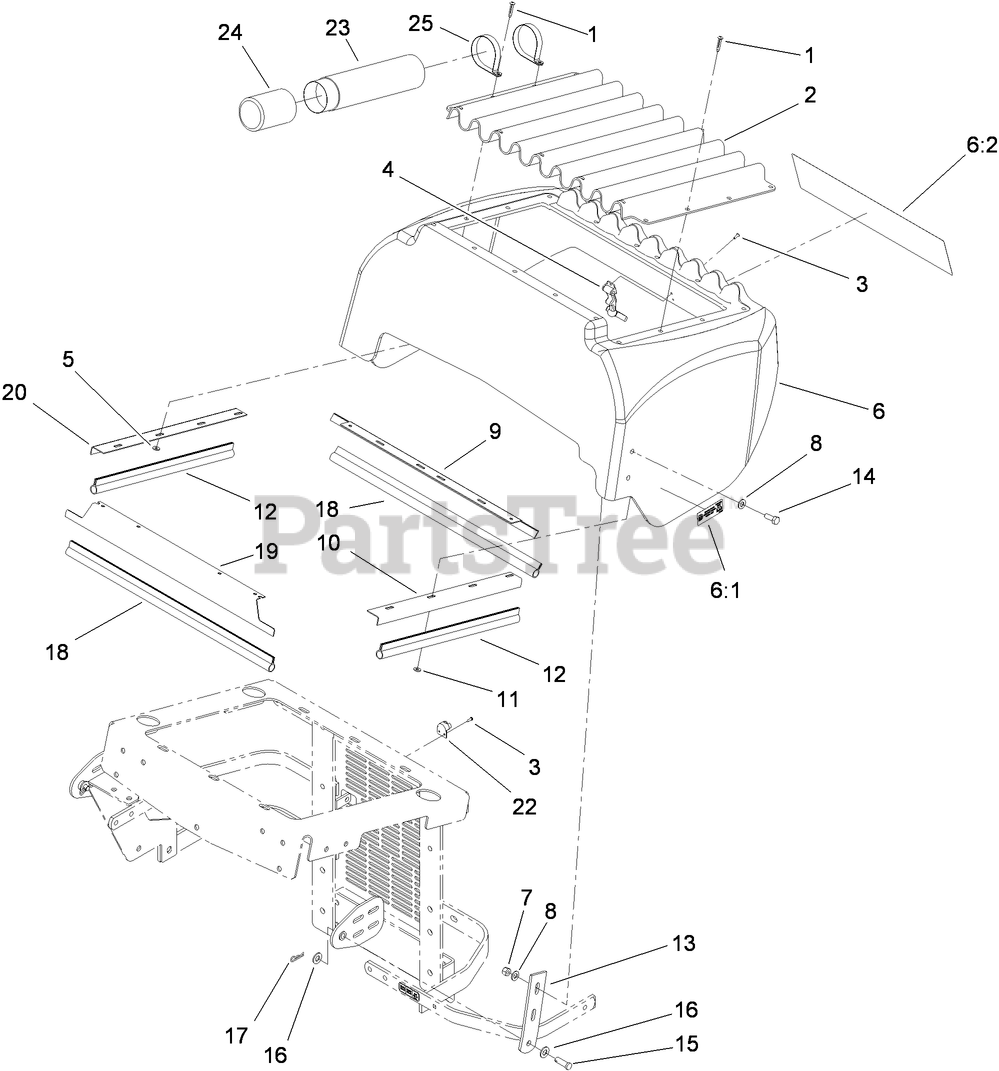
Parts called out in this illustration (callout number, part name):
2	SCREEN-RADIATOR
3	RIVET
4	LATCH-RUBBER
5	WASHER-SPRING
6	HOOD ASM
6:1	DECAL-LOW SULFUR
7	NUT-LOCK, NI
8	WASHER-PLAIN
9	ANGLE-RADIATOR, BOTTOM
10	ANGLE-RADIATOR, LH
11	WASHER-FLAT
12	SEAL-TRIM
13	PLATE-HINGE, HOOD
14	SCREW-HH
15	PIN-CLEVIS
16	WASHER-FLAT
17	PIN-COTTER
18	SEAL-TRIM
19	ANGLE-RADIATOR, TOP
20	ANGLE-RADIATOR, RH
22	KEEPER-LATCH, RUBBER
23	TUBE-MANUAL
24	CAP-HOUSING
25	CLAMP-R
